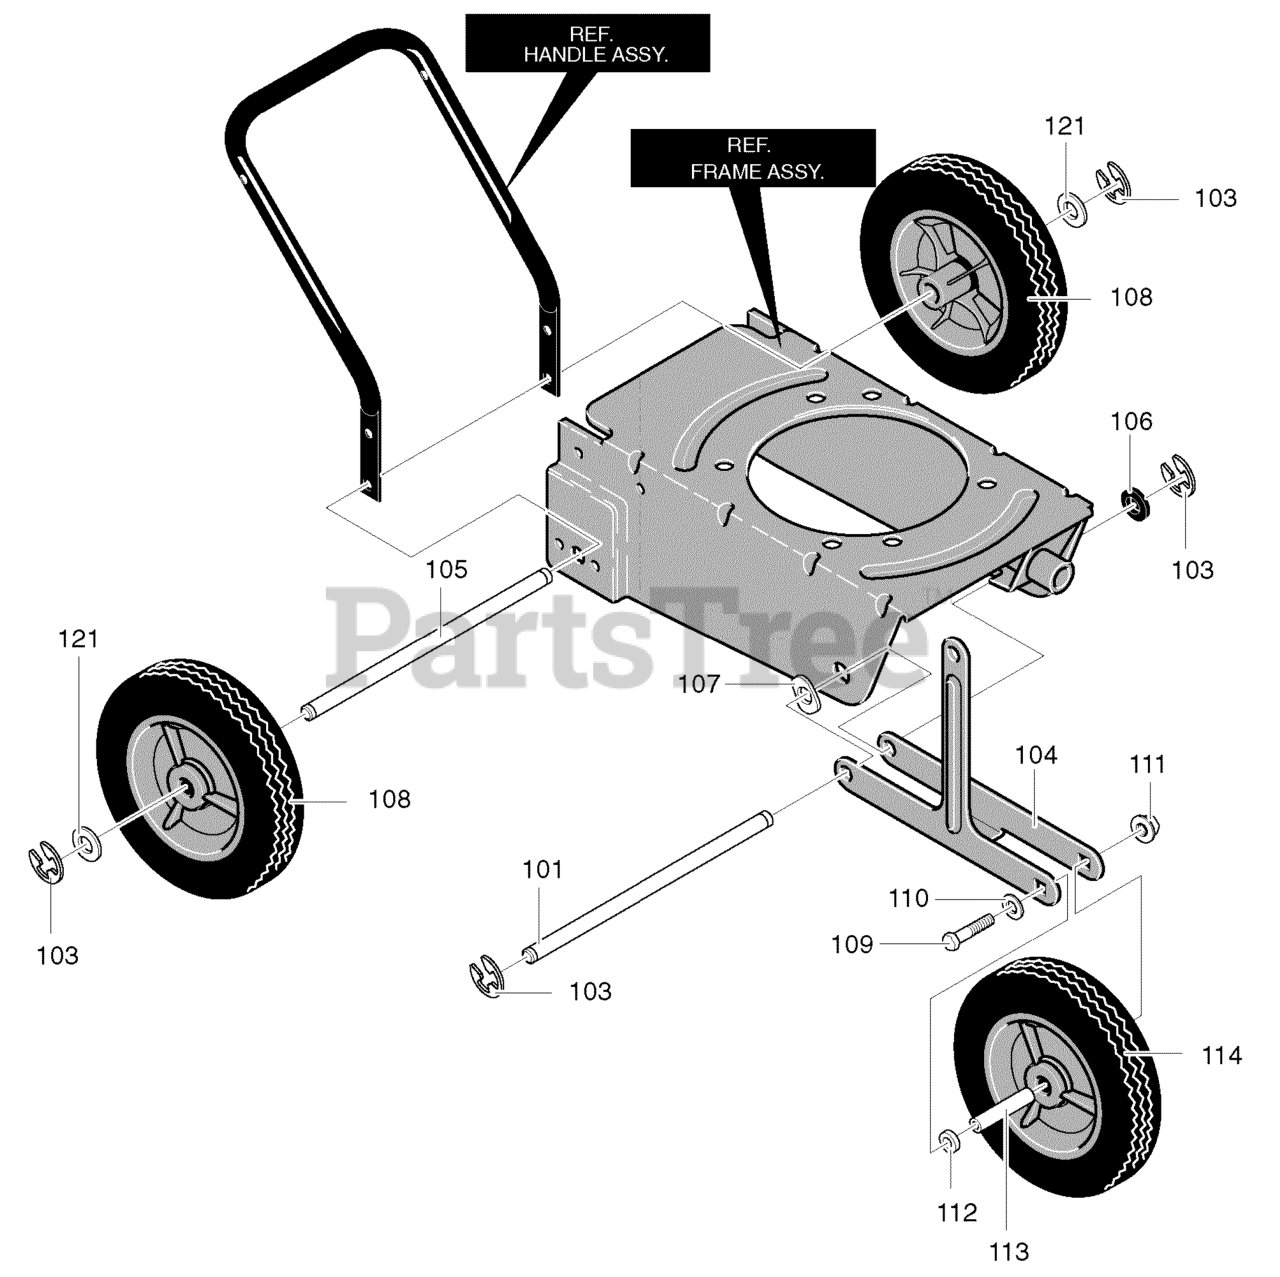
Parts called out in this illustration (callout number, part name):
101	Rod, Axle Front
103	Ring, Ret E.
104	Arm, Front Wheel
105	Rod, Axle R.
106	Flat washer
107	Spring Washer
108	Tire & Rim
110	Flat washer
111	NUT, 5/16-18
112	Washer, Nylon
113	Spacer, Sleeve
114	Tire & Rim
121	Flat washer
